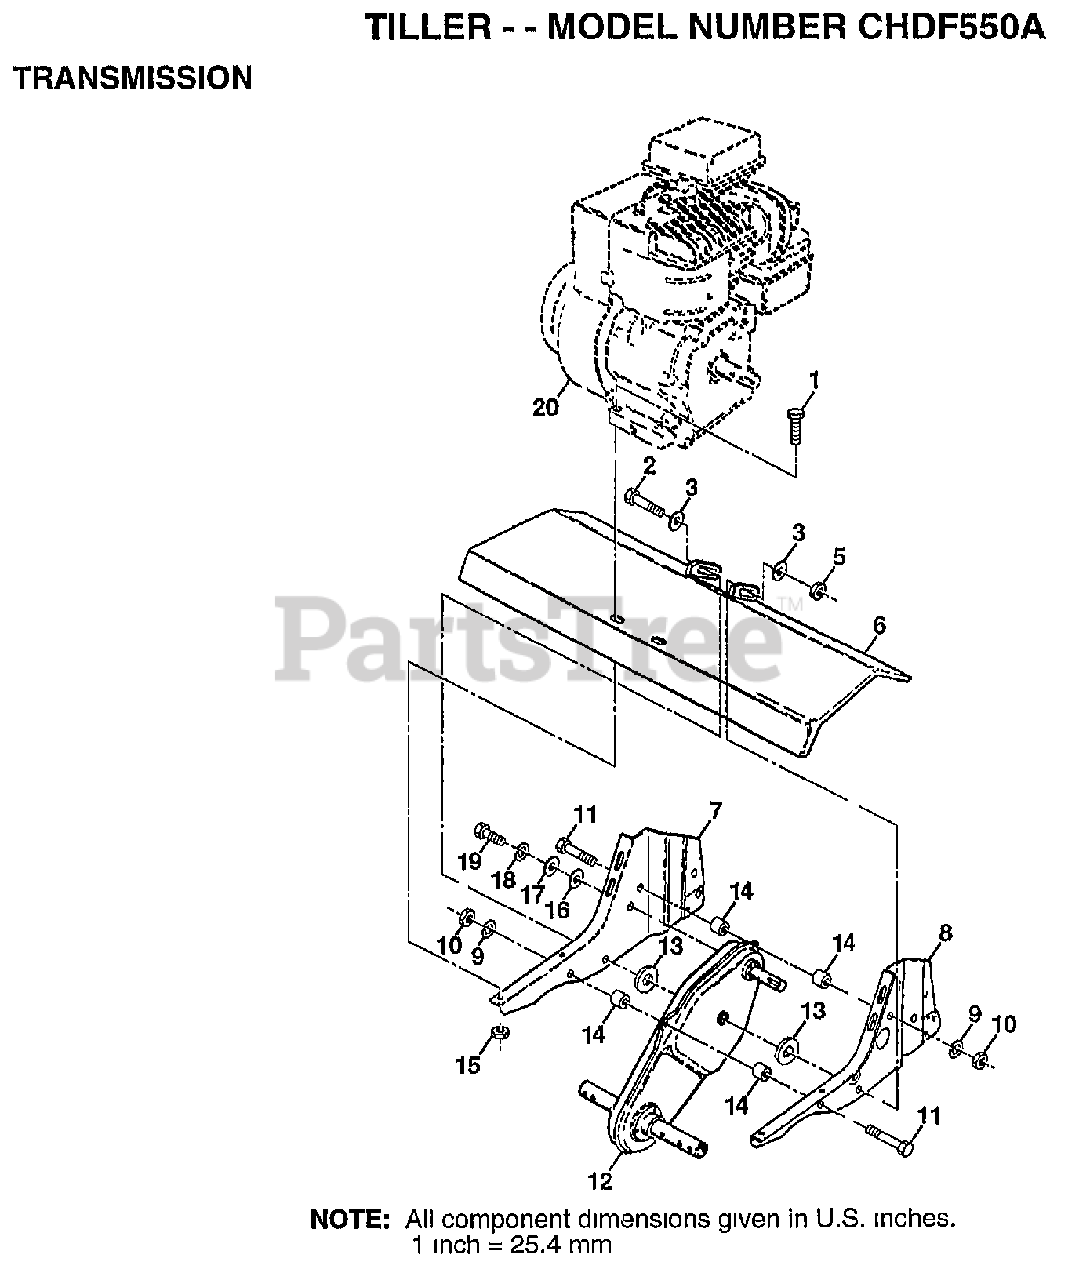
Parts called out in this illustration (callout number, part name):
1	BOLT.HEX.5/16-1.5
2	BOLT HEX 3/8-16
3	WASHER
5	NUT
6	SHIELD TINE
8	BRACKET.ENG.LH.
9	LOCKWASHER
10	NUT.HEX.5/16-18
14	SPLIT SPACER RT
16	WASHER
17	WASHER
18	LOCKWASHER
19	BOLT
20	ENGINE, B&S
